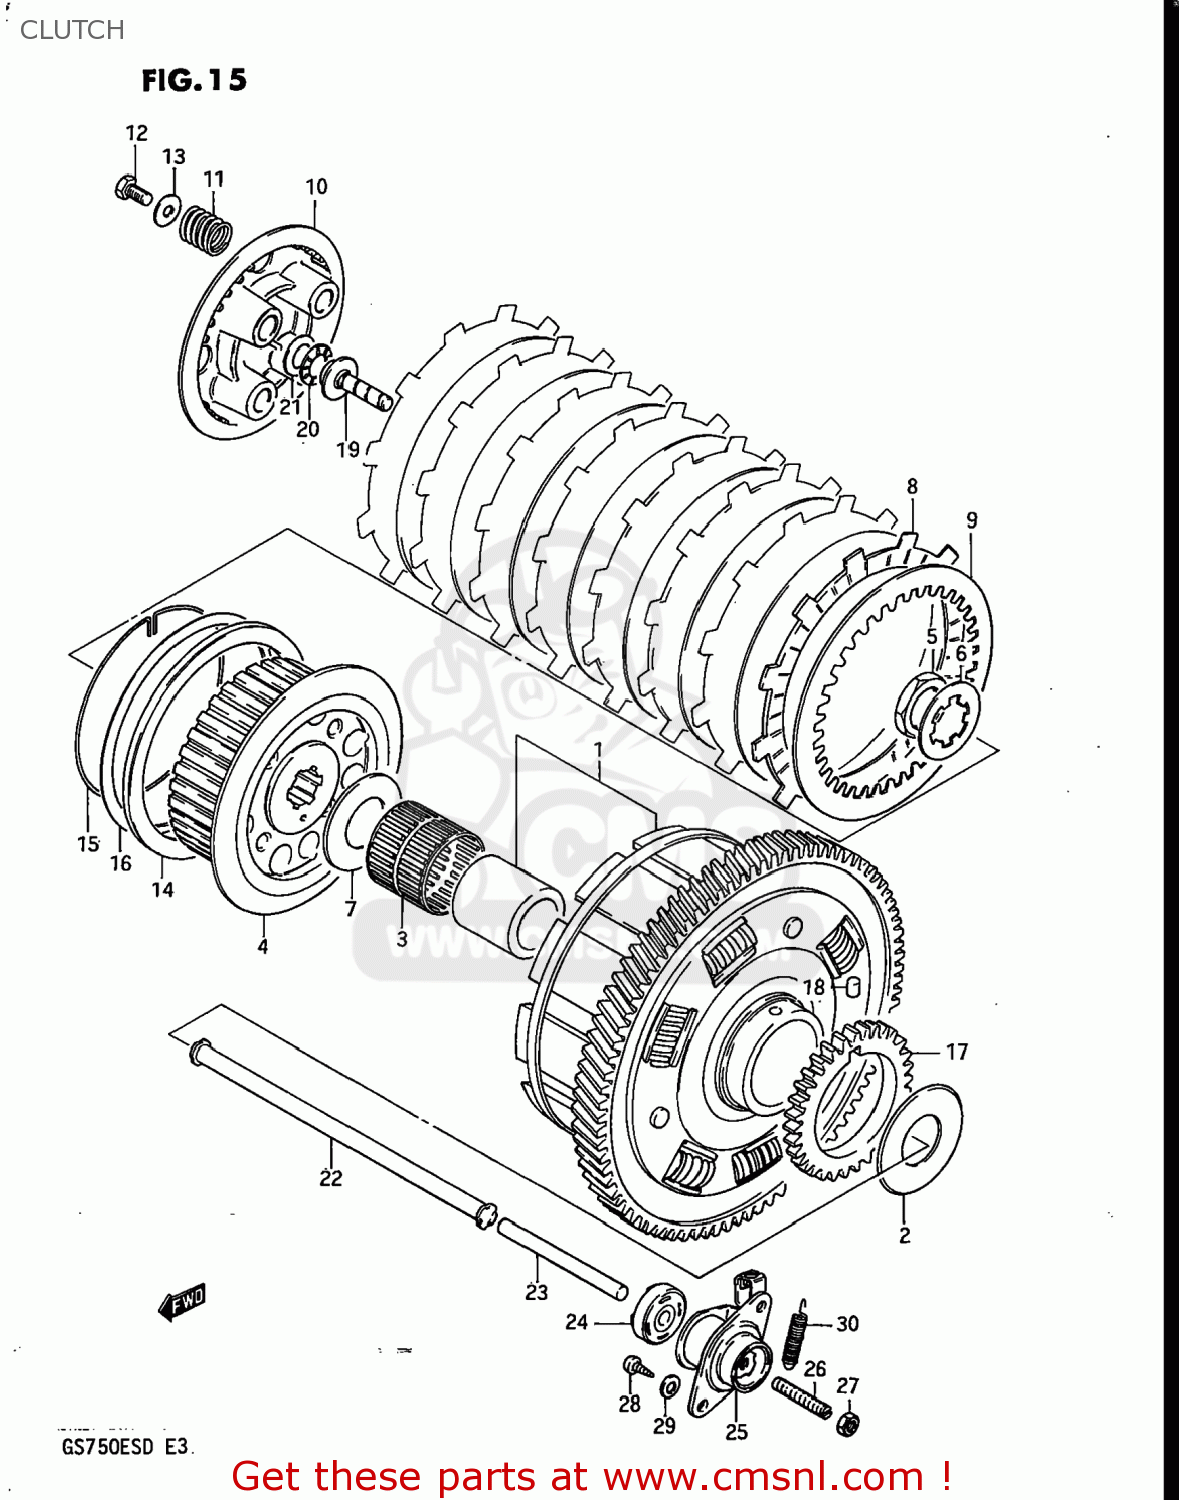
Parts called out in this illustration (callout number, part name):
1	GEAR ASSEMBLY,PRIMARY DRIVE
2	WASHER(25X54X2.5)
3	BEARING(35X40X39.8)
4	HUB,CLUTCH SLEEVE
5	NUT
6	WASHER,LOCK
7	WASHER
8	PLATE,CLUTCH DRIVE (MCA)
9	PLATE,CLUTCH DRIVEN(T:2.0) (NAS)
10	PLATE,CLUTCH PRESSURE
11	SPRING
12	BOLT, UPPER
13	WASHER
14	SEAT,WAVE WASHER
15	RING,STOPPER
16	WASHER
17	GEAR,OIL PUMP DRIVE
18	PIN(6X6)
19	PIECE,CLUTCH PUSH
20	BEARING(15X28X2)
21	WASHER
22	ROD,CLUTCH PUSH
23	ROD,CLUTCH PUSH,L
24	OIL SEAL
25	SCREW ASSY,CLUTCH RELEASE
26	SCREW
27	NUT 6MM
28	SCREW
29	WASHER
30	SPRING
